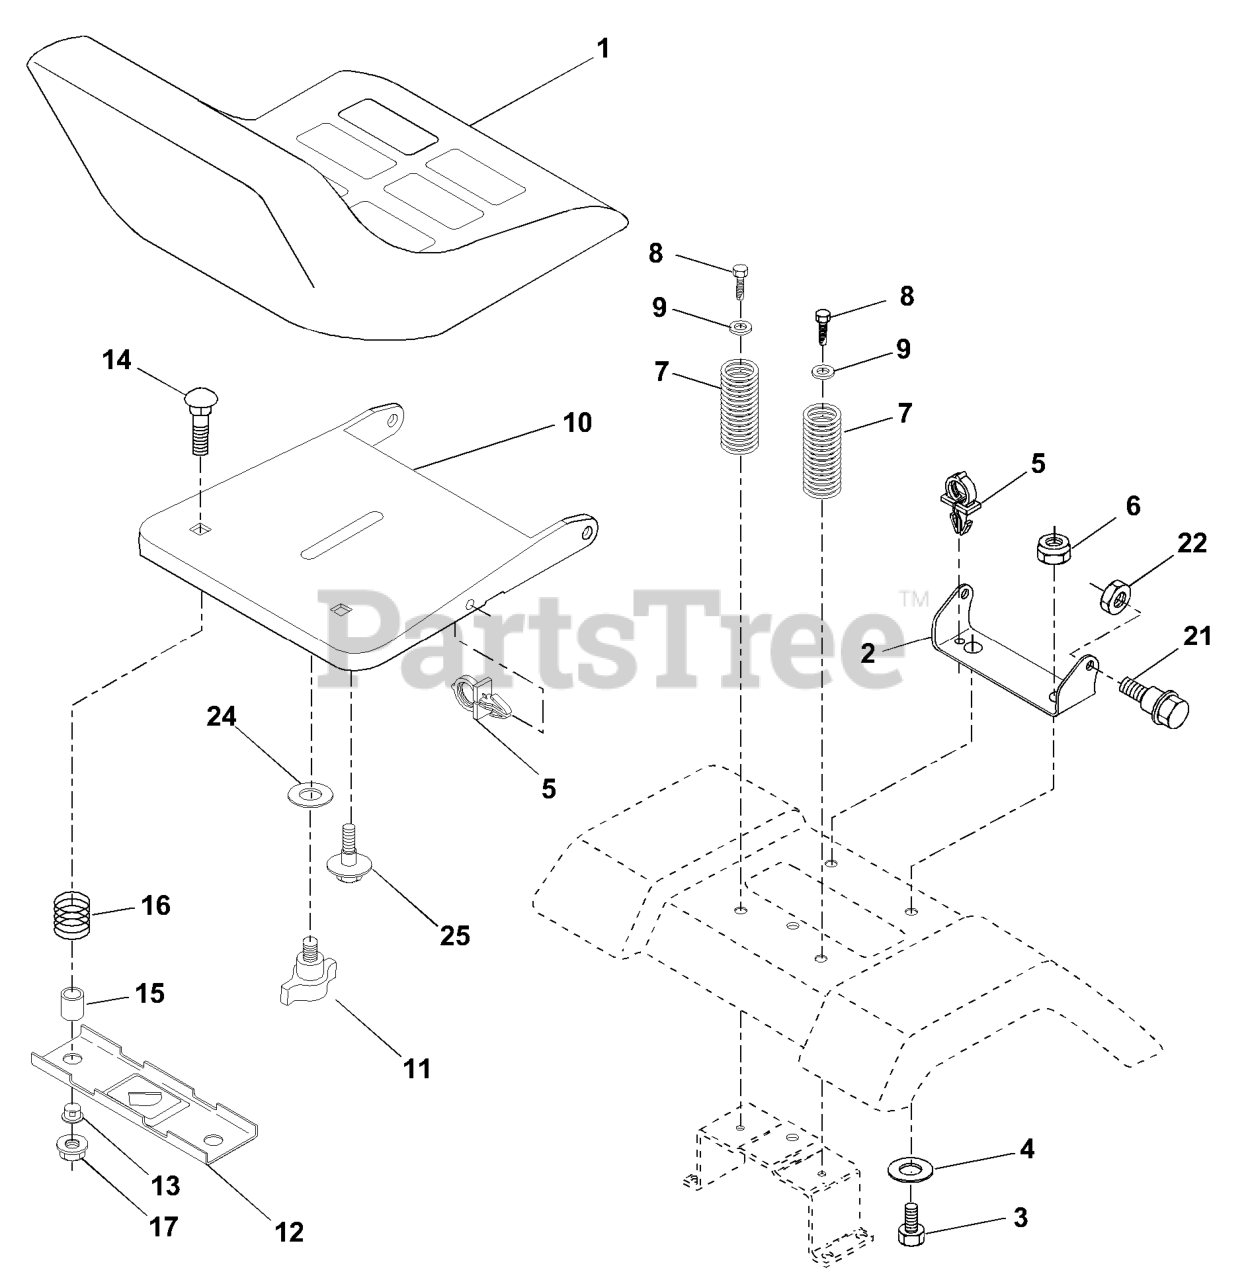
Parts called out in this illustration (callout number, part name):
1	SEAT, GRAY
2	SEAT PIVOT BRKT
3	BOLT, HEX 3/8-16X1
6	NUT
7	SPRING COMPRESSION
8	SCREW 3/8-16X1
9	WASHER
10	PAN, SEAT
11	KNOB.SEAT.ADJ.WINGNUT
12	BRKT SWITCH
14	BOLT.ROUND.HEAD.SQUARE.NECK
15	SPACER SPLIT
16	SPRING COMPRESSED
17	NUT T
21	BOLT.SHOULDER.5/16-18
22	NUT.71038.31-18.HEX.NYLOCK
25	BOLT,SHOULD
